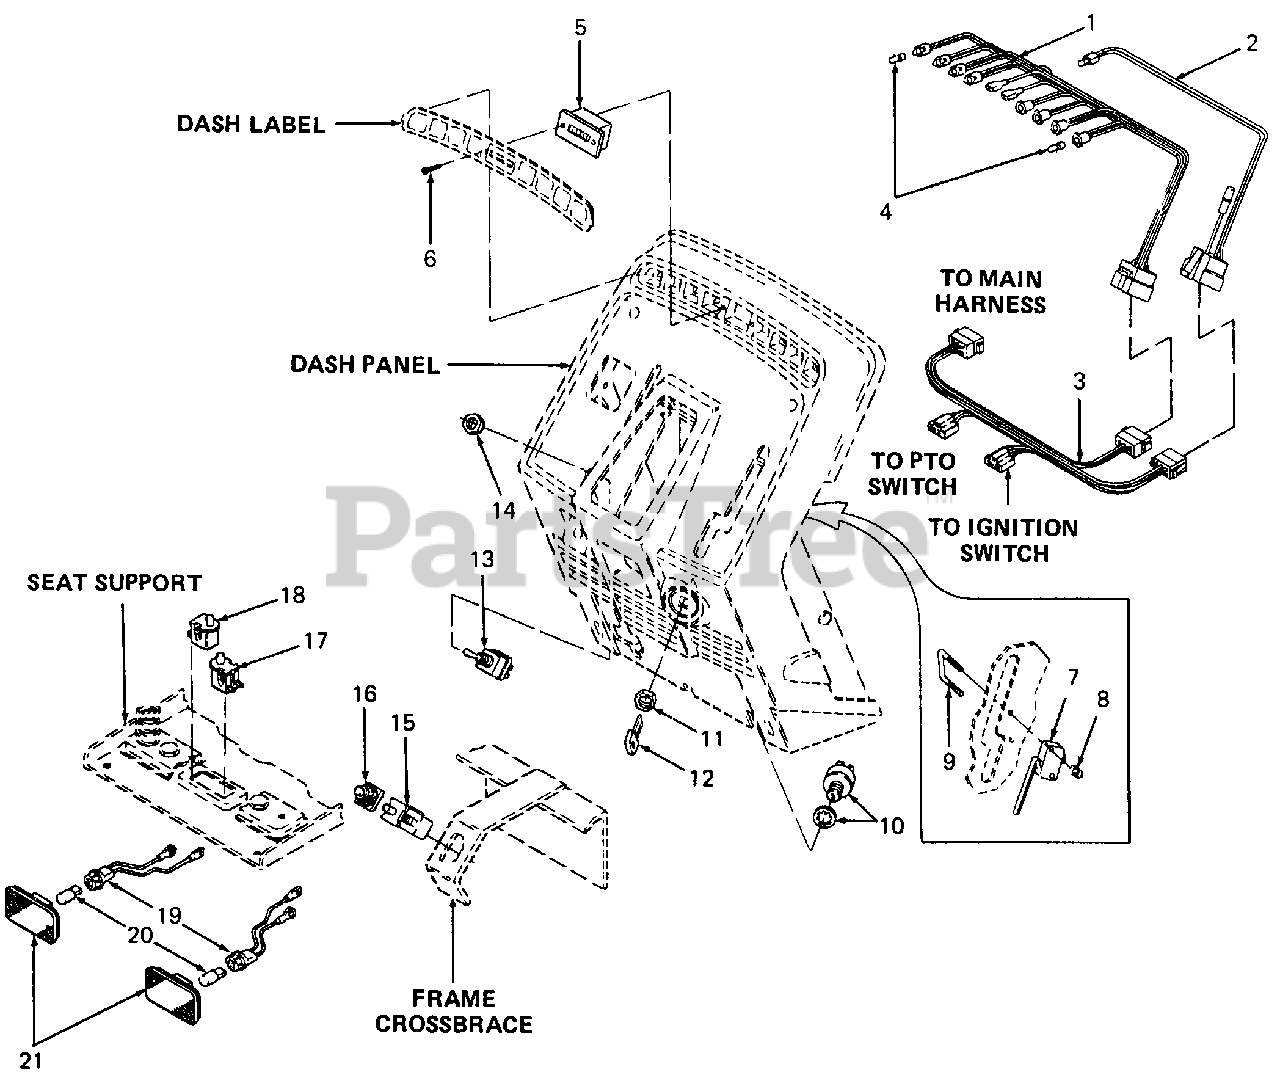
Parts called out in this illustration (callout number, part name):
1	Harness, Indicator Wire
2	Harness, Indicator Adapter
3	Harness, Pedestal
4	Bulb, Indicator
5	Hour Meter
6	Screw, Truss Hd Tapp, #6 X .62 Lg
7	Switch, Reverse
8	Nut, Hex Insert Lock, #4-40
9	Screw, Switch
10	Switch, Ignition
11	Nut, Ignition Switch
12	Key, Ignition (Set of 2)
13	Switch, PTO
14	Nut, Hex, 1/2-27 X .100 Thk
15	Switch, Interlock
16	Boot, Switch
17	Switch, Snap Mount - Normally Open (Black)
18	Cable Assy, Tail Light
19	Bulb, Tail Light
20	Lens Assy, Tail Light
21	Diode Assy
